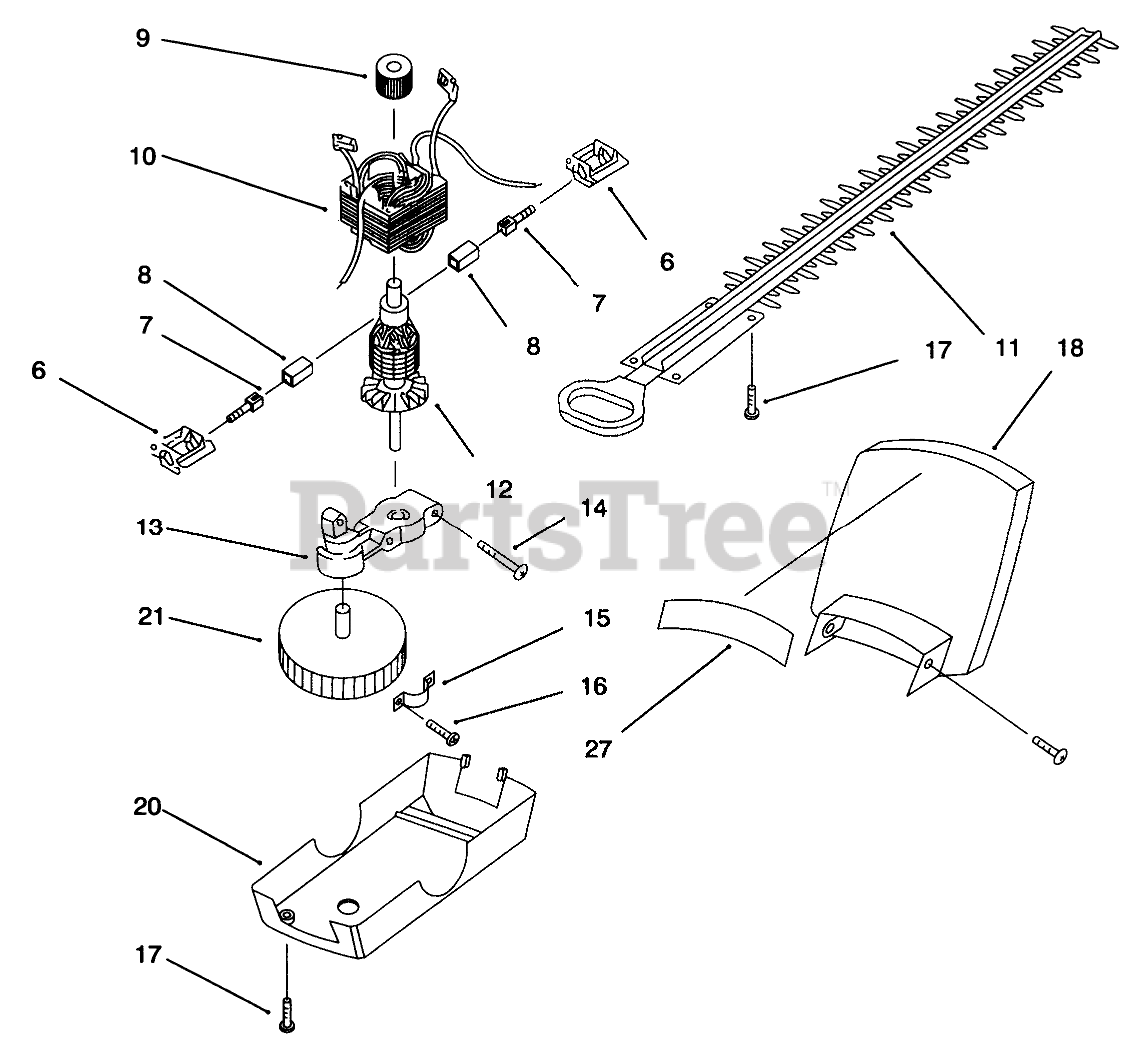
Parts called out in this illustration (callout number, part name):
6	HOLDER - BRUSH TUBR
7	ASSEMBLY - BRUSH
8	TUBE - BRUSH
9	HEAT SINK W/BEARING
10	ASSEMBLY - FIELD
13	BEARING PLATE W/BEARINGS
14	SCREW
15	STRAP - BEARING
16	SCREW
18	GUARD - BLADE
20	COVER - BLADE
